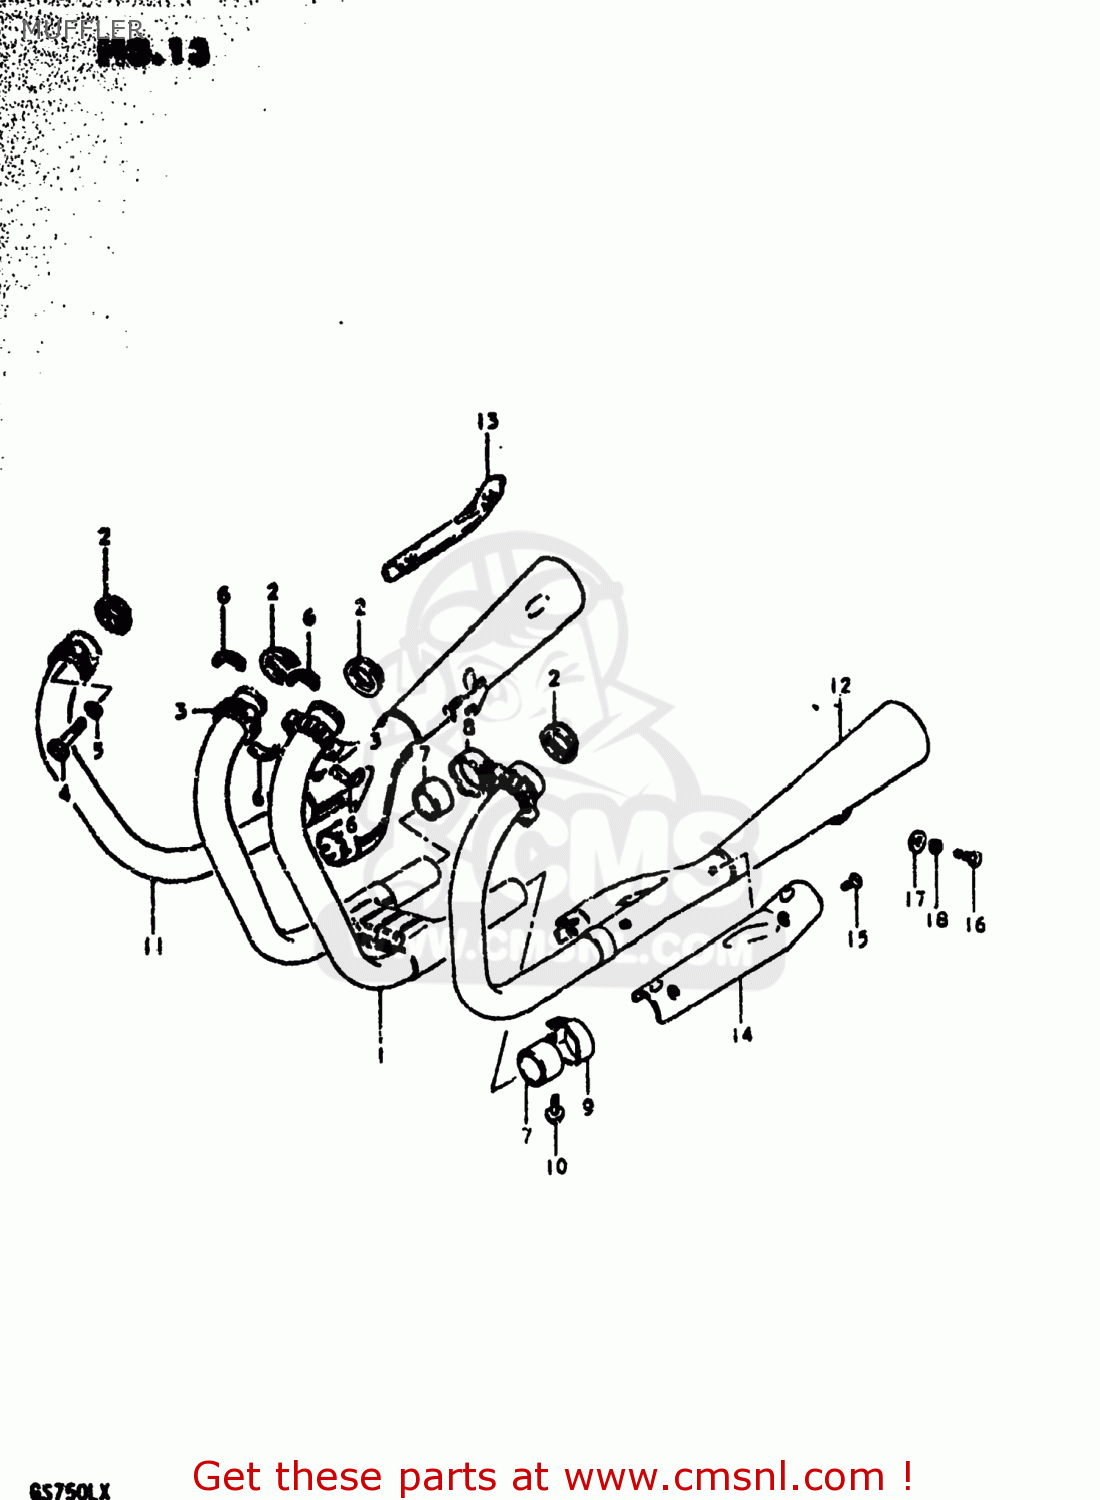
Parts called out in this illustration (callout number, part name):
1	PIPE,EXHAUST
2	GASKET,EXHAUST PIPE (NAS)
3	CLAMP,EXHAUST PIPE
4	BOLT
5	LOCK WASHER
6	PLATE,EXHAUST
7	CONNECTOR,MUFFLER
8	CLAMP,MUFFLER CONNECTOR,R
9	CLAMP,MUFFLER CONNECTOR,L
10	BOLT
11	BODY,MUFFLER
12	BODY,MUFFLER
13	COVER,MUFFLER,RIGHT
14	COVER,MUFFLER,LEFT
15	SCREW
16	BOLT 10X30
17	WASHER
18	LOCK WASHER
